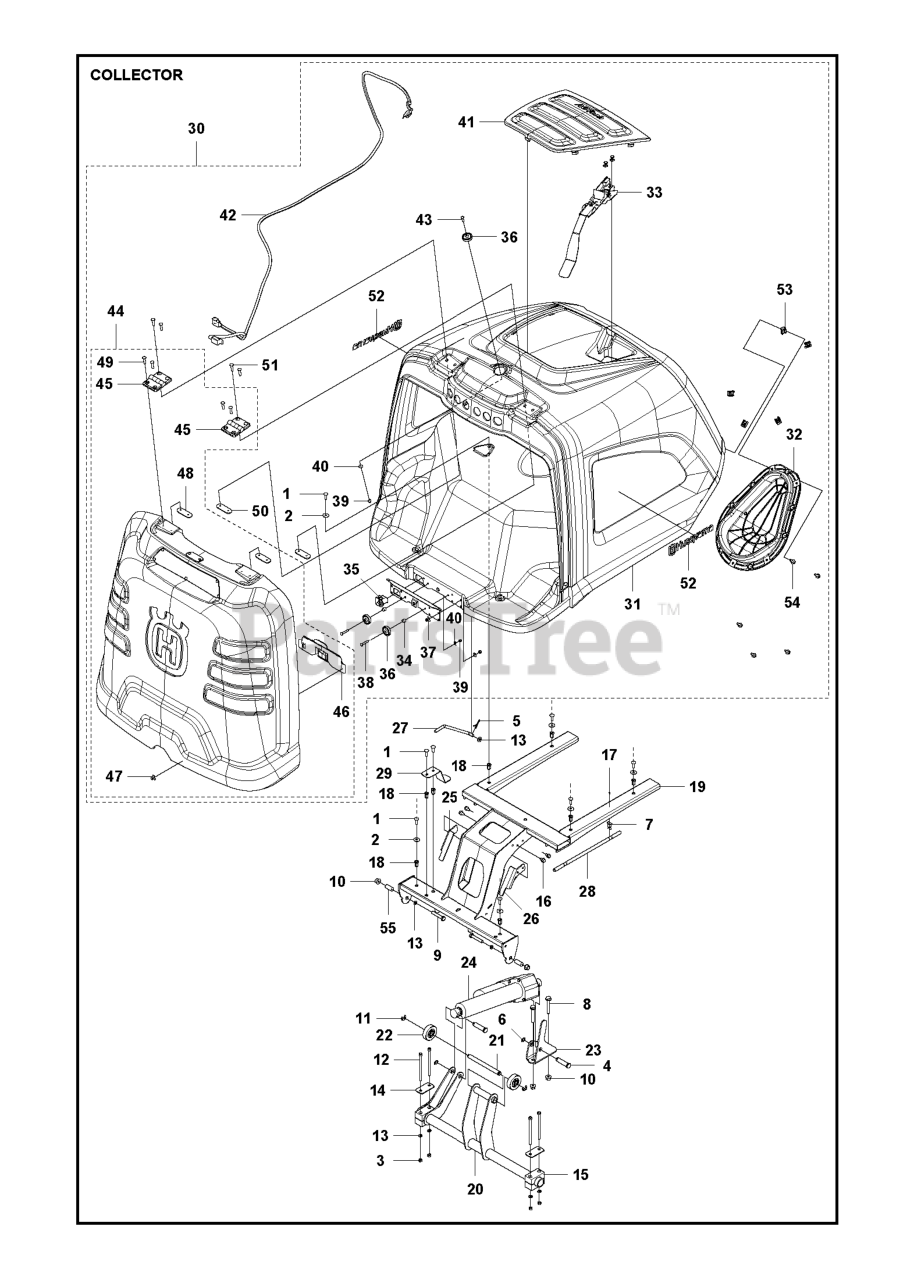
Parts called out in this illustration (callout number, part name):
3	NUT FLANGE - M6
8	SCREW EHHFM
9	SCREW
10	NUT FLANGE
11	RETAINING RING
12	SCREW IHSCM.
13	WASHER BRB 8.4X17
35	REVERSE SWITCH
52	DECAL.HUSQVARNA.210MM
54	SCREW
